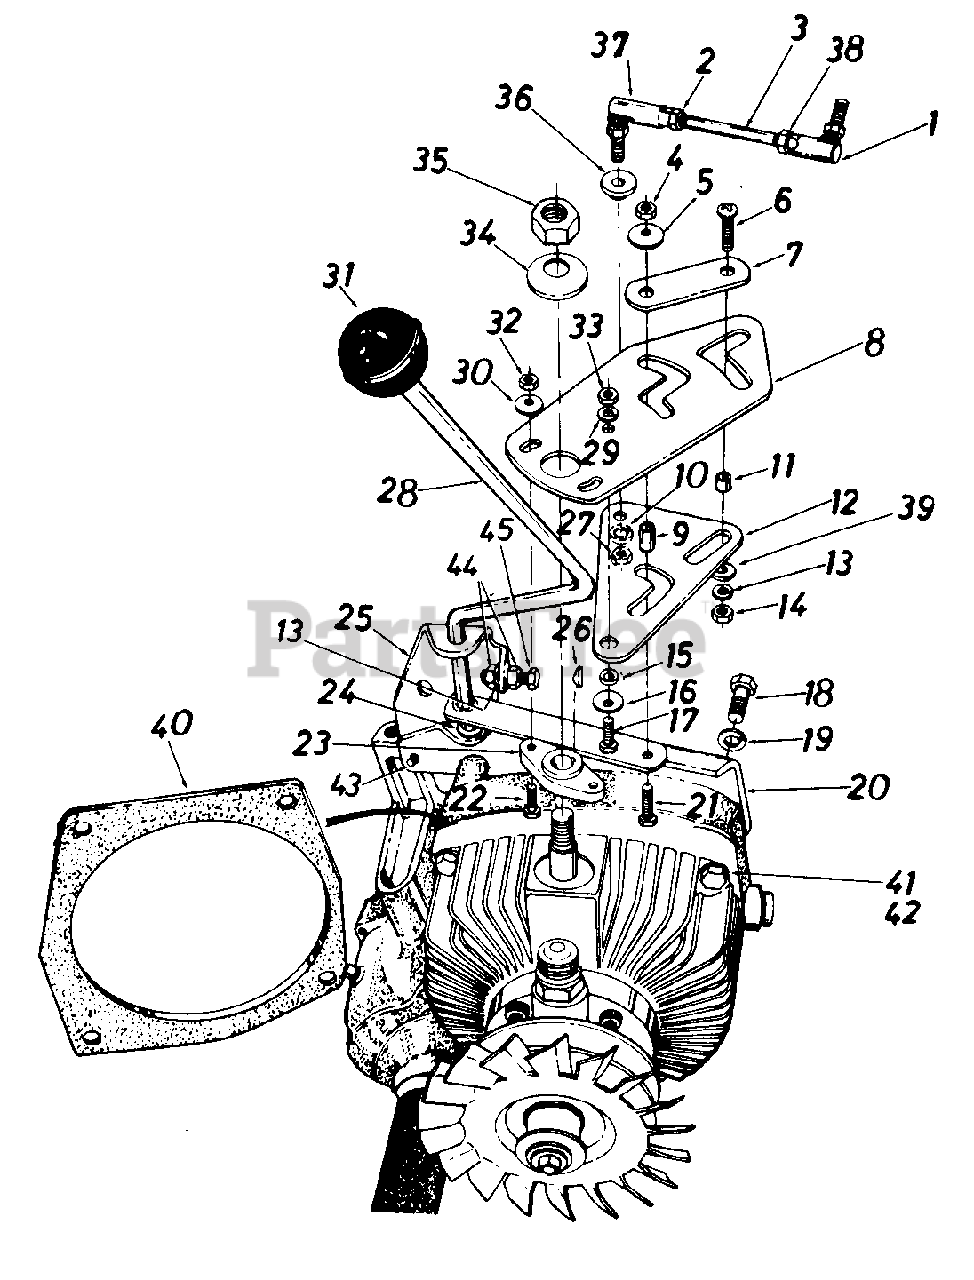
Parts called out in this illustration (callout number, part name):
1	Ball Joint Ass'y. 3/8-24 Thd.
2	Hex Nut 3/8-24 Thd. (L.H. Threads)
3	Control Rod 3/8-24 x 3.75"
4	Hex Nut 3/8-24 Thd.
5	Fl-Wash. .385" I.D. x .87"
6	Truss Mach. Scr. Phil. 5/16-18 x 1.00" Lg.
7	Locking Link
8	Pintle Main Control Plate
9	Spacer.83" Lg.
10	L-Wash. 3/8" I.D.
11	Spacer.35" Lg.
12	Pintle Drive Plate
13	L-Wash. 5/16" I.D.
14	Hex Nut 5/16-18 Thd.*
15	Spacer .38" I.D. x .227" Lg.
16	Fl-Wash. .385" I.D. x .87"
17	Hex Bolt 3/8-24 x 1.00" Lg.
18	Hex Bolt 3/8-16 x 1.0" Lg. (Grade 5)
19	L-Wash. 3/8" I.D.
20	Shift Lever Bracket
21	Hex Bolt 3/8-24 x 1.25" Lg.*
22	Hex Bolt 1/4-28 x .75" Lg.
23	Pintle Hub
24	Nyliner .375" Dia. x .140
25	Shift Lever Bracket-Upper
26	#5 Hi-Pro Key 1/8 x 5/8 Dia.
27	Hex Nut 3/8-24 Thd.
28	Shift Lever Ass'y.
29	L-Wash. 3/8" I.D.
30	Fl-Wash. 385" I.D. x 37"
31	Gear Shift Knob
32	Hex Nut 1/4-28 Thd.
33	Hex Nut 3/8-24 Thd.
34	Bell-Wash. .505" I.D. x 1.00"
35	Hex Nut 1/2-13 Thd.
36	Shld. Spacer .625" I.D.
37	Ball Joint Ass'y. 3/8-24 L.H. Thd.
38	Hex Jam Nut 3/8-24 Thd.
39	Fl-Wash. .330" I.D. x 1.25"
40	Gasket
41	Hex Bolt 3/8-16 x 2???75" Lg. (Grade 5)
42	Fl-Wash. 385n l-.D. x .62"
43	Hex Wash. Hd. Self-Tap Scr. 1/4-20 x .50" Lg.
44	Hex Nut 5/16-24 Thd.
45	Hex Bolt 5/16-24 x 1 on Lg.
